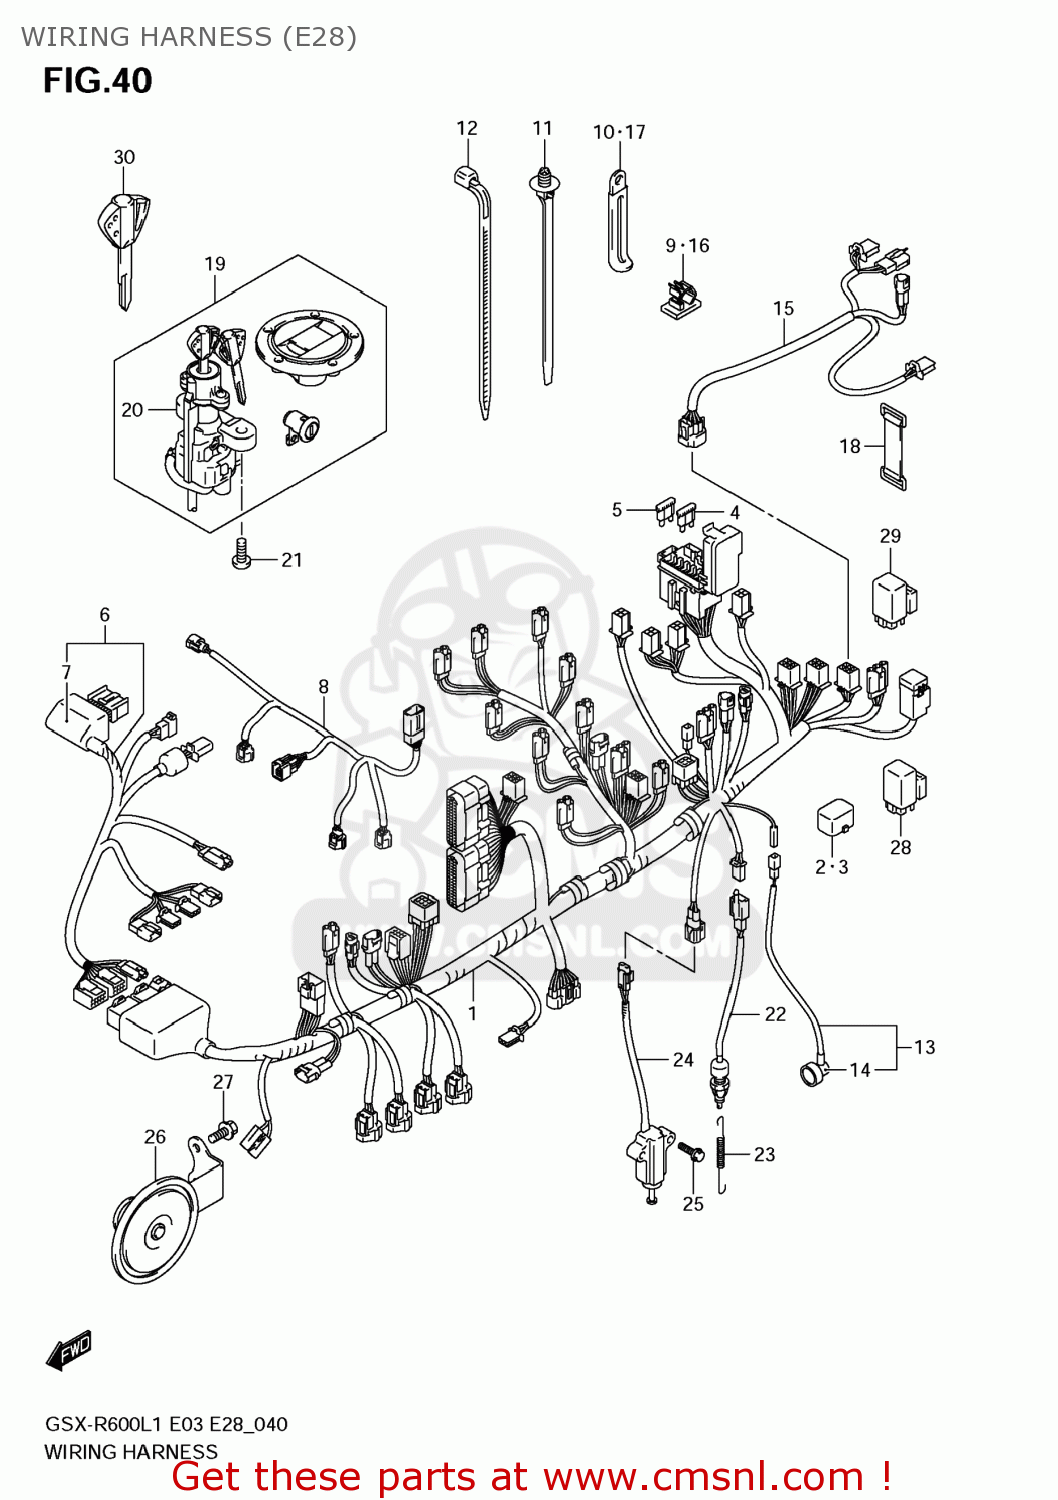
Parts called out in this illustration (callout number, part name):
1	HARNESS,WIRING NO.1
2	CAP,TS
3	CAP,CO ADJUST
4	FUSE(10A)
5	FUSE(15A)
6	HARNESS,WIRING NO.2
7	COVER,CONNECTOR
8	HARNESS,WIRING NO.3
9	CLAMP(L:95)
10	CLAMP(L:145)
11	CLAMP(L:154)
12	CLAMP(L:125)
13	WIRE,OIL PRESSURE SWITCH LEAD
14	CAP,OIL PRESSURE SWITCH
15	WIRE,RR COMB LEAD
16	CLAMP
17	CLAMP(L:45)
18	BAND
19	LOCK SET
20	LOCK ASSY,STEERING
21	BOLT(8X20)
22	SWITCH ASSY,STOP LAMP
23	SPRING
24	SWITCH ASSY,SIDE STAND
25	BOLT
26	HORN ASSY
27	BOLT
28	RELAY ASSY
29	RELAY ASSY
30	KEY,BLANK(IMMOBII)
